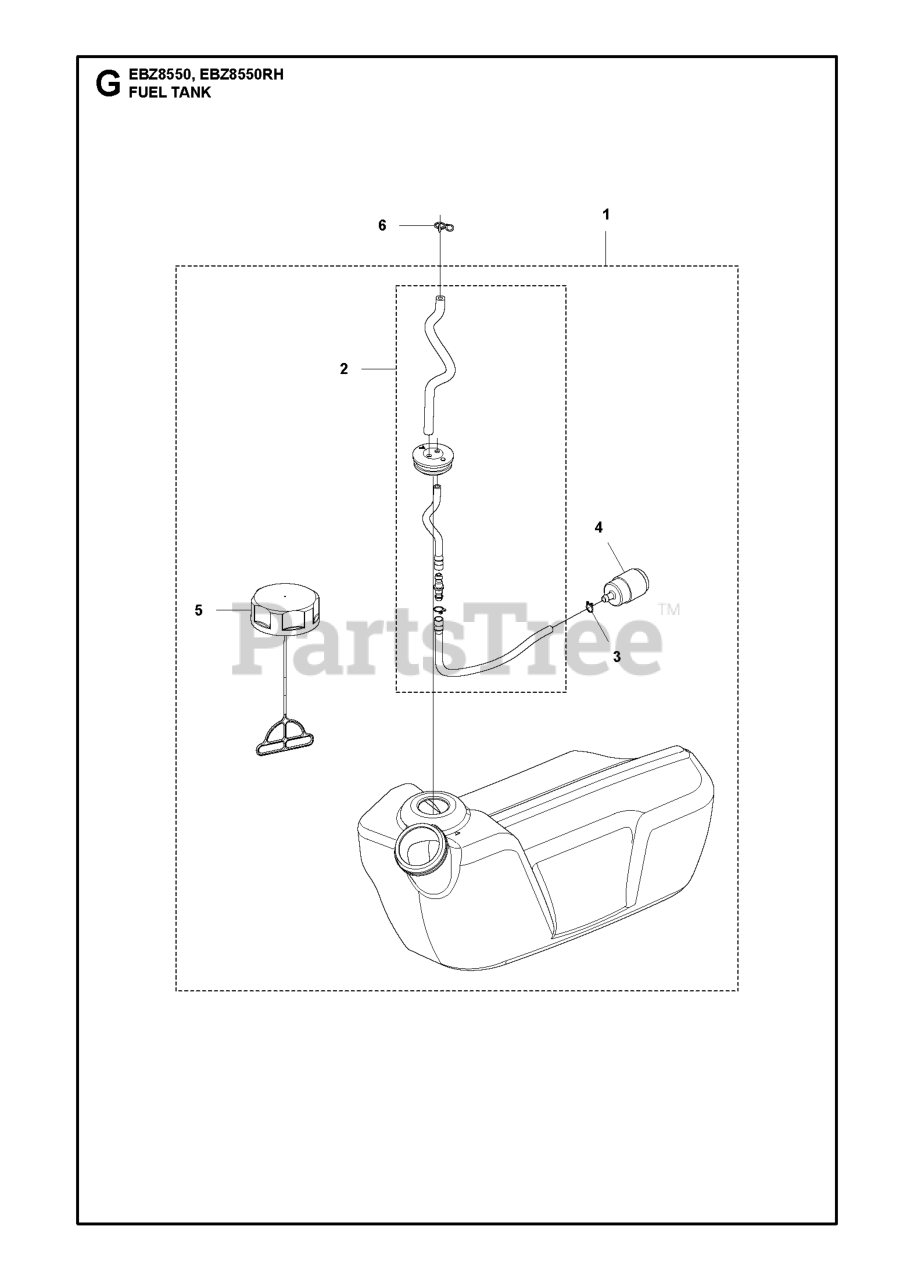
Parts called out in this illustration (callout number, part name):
1	TANK ASSY
2	PIPE ASSY
3	CLIP
4	FILTER ASSY
5	ASSY FUEL CAP
6	CLIP
